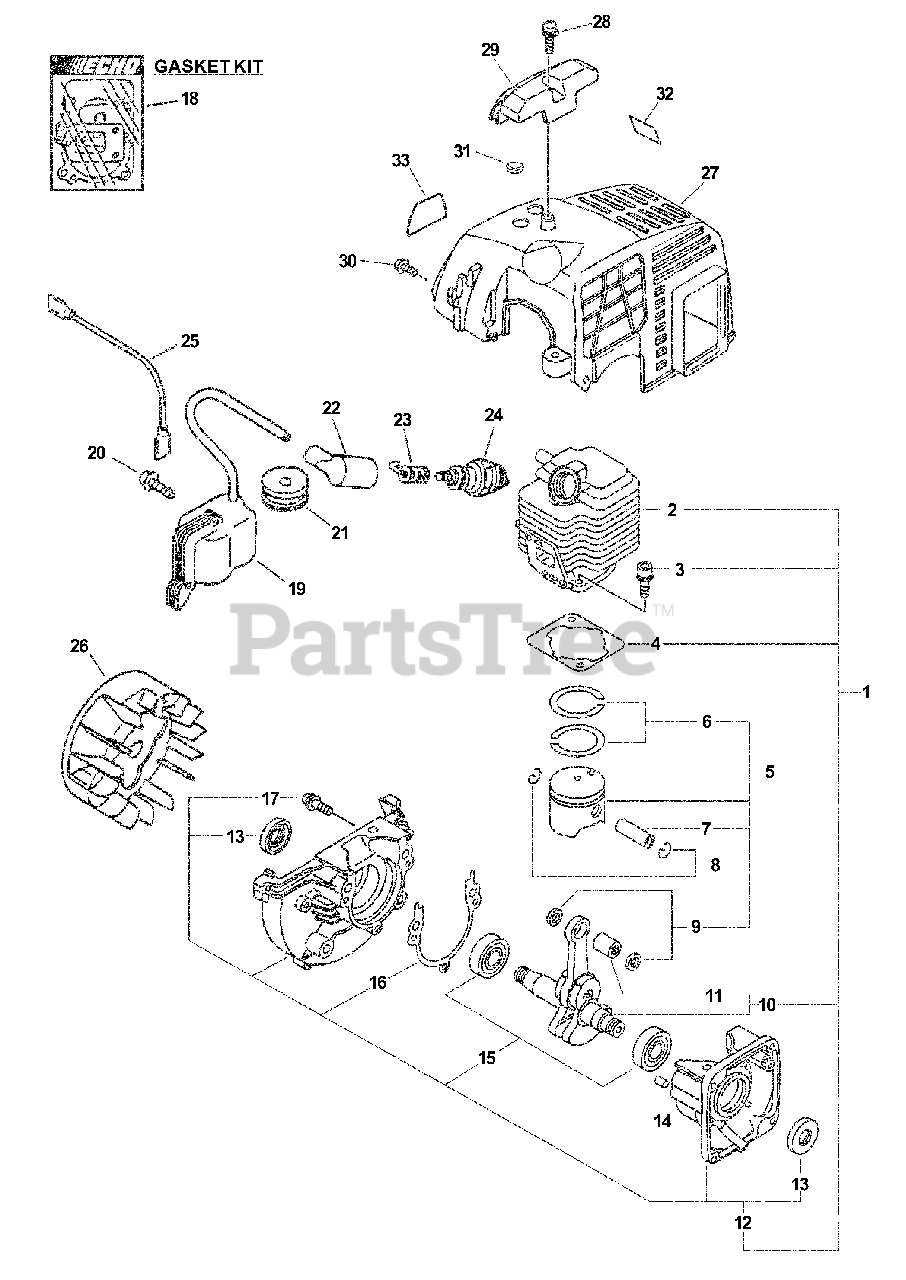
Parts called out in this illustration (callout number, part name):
1	SHORT BLOCK
2	CYLINDER
3	BOLT 5×22
4	GASKET, CYLINDER
5	PISTON KIT
6	RING, PISTON
7	PIN, PISTON 8
8	RING, SNAP
9	WASHER, THRUST
10	CRANKSHAFT ASSY
11	BEARING, NEEDLE 8
12	CRANKCASE KIT
13	SEAL, OIL 12
14	PIN, LOCATING 4
15	BEARING, BALL - 6201 C3
16	GASKET, CRANKCASE
17	BOLT 5×28
18	GASKET KIT
19	COIL, IGNITION
20	SCREW 4×22
22	CAP, SPARK PLUG
23	TERMINAL, SPARK PLUG
24	SPARK PLUG - BPM7A
25	LEAD
26	FLYWHEEL
27	COVER, ENGINE
28	SCREW 5×16
29	GUARD, TOP - GRAY
30	SCREW 4×12
32	LABEL, CAUTION - HOT
33	LABEL, MODEL
